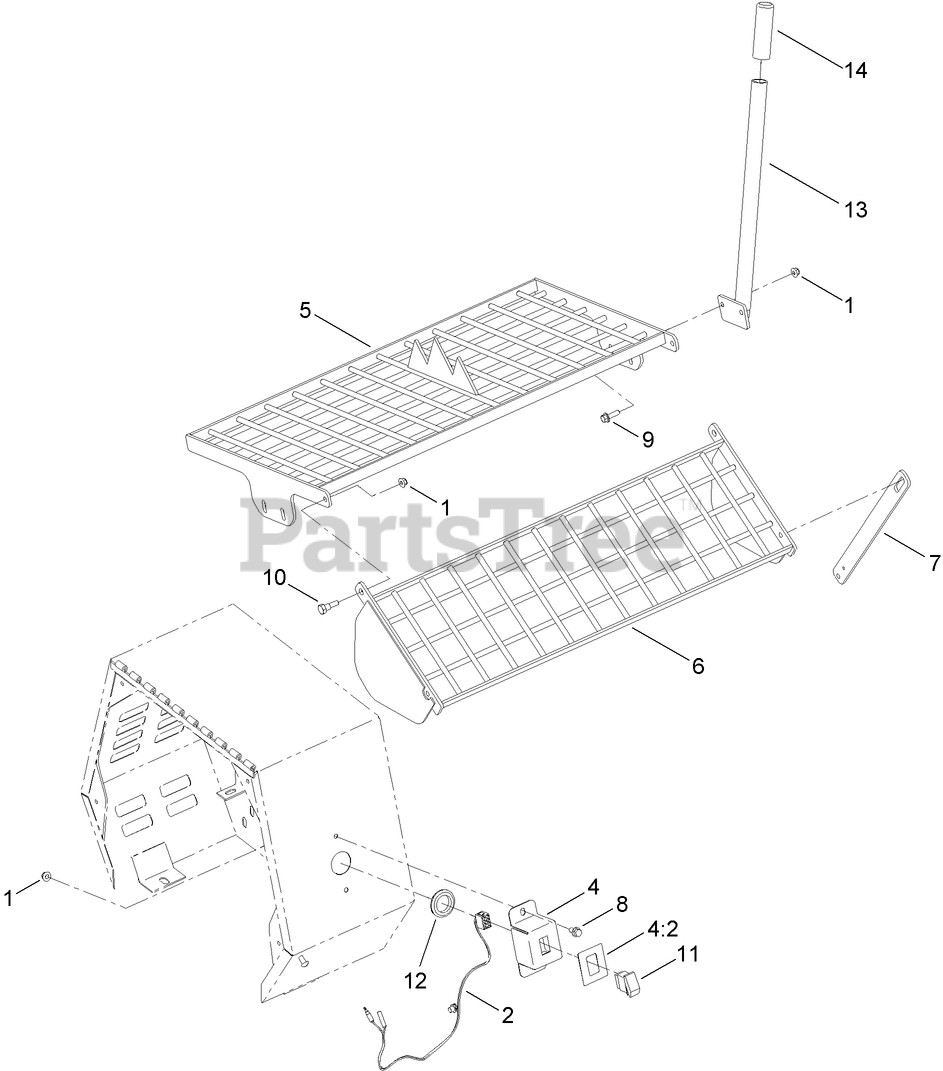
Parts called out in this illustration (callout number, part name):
1	NUT-HF, NI
2	HARNESS-WIRE, MIXER
4	SWITCH PLATE HOUSING ASM
4:2	DECAL-STOP, ENGINE
5	GUARD-STATIONARY
6	GUARD-MOVABLE
7	LIFTER-GUARD, MOVABLE
8	SCREW-HHF
9	SCREW-HHF
10	BOLT-SHOULDER
11	SWITCH
12	GROMMET
14	GRIP-HAND
